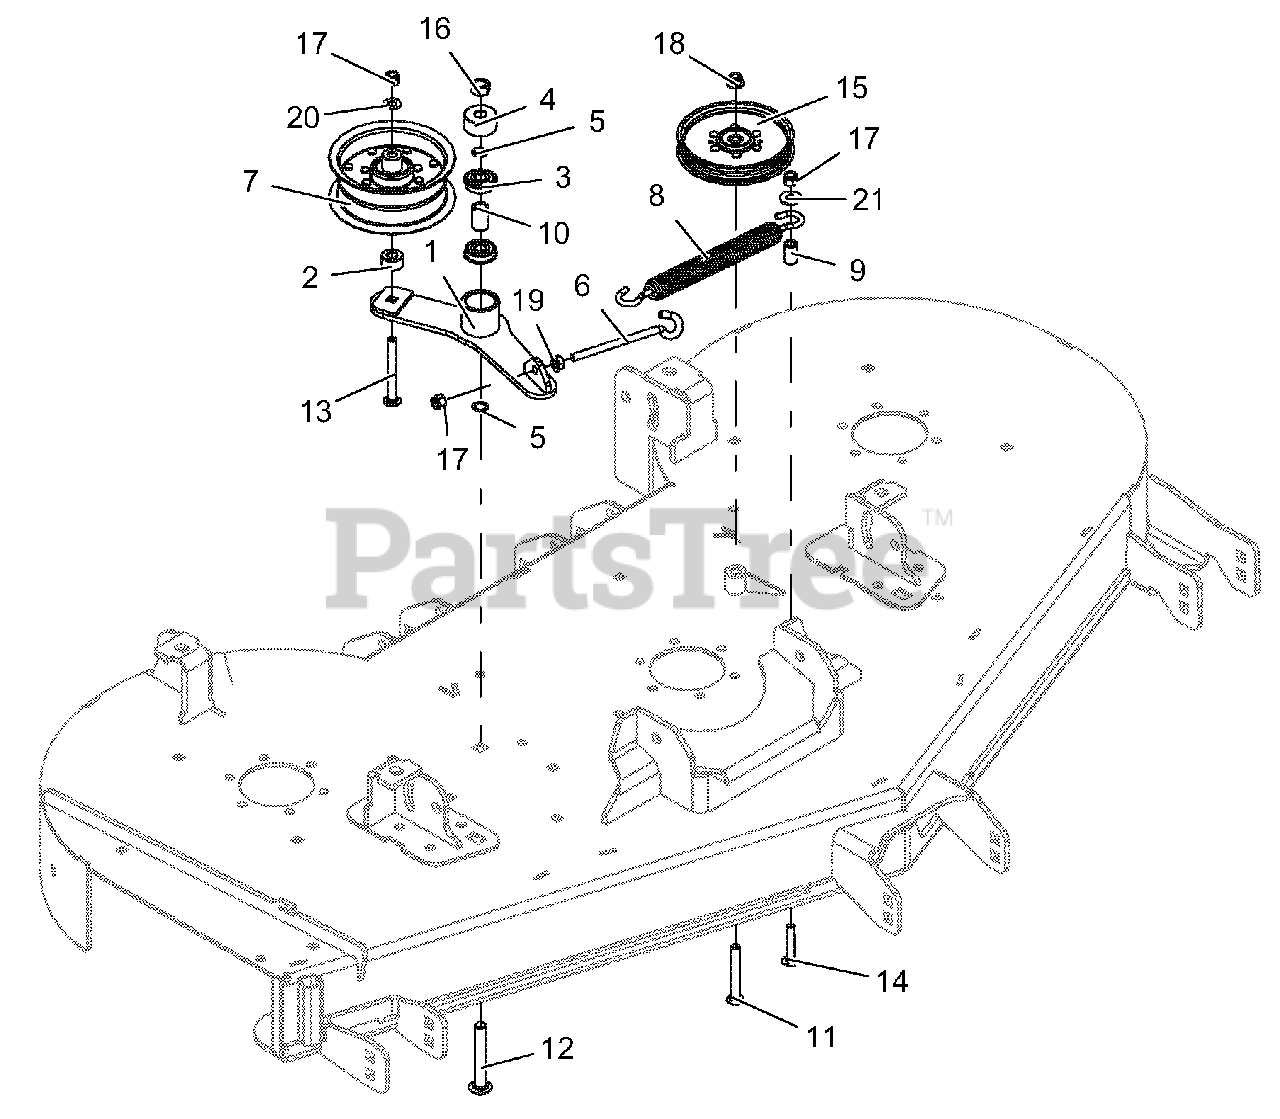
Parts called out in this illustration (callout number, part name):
1	WLDMT, IDLER ARM 61
2	SPACER, .437 x 1.00 x .58 SMLS
3	BRG, BALL .501 x 1.38 x .438 SEALED
4	SPCR, IDLER ARM
5	WASHER-FLAT-STL, .500 x .750 x .020
6	BOLT, EYE .38-16 x 6.00 .62 DIA
7	PULLEY, FLAT 5.00 x 2.36 x .375
8	SPRG, EXTENSION
9	BUSH., S .391 x .622 x .95 ST REV A
10	SPACER, .510 x .750 x 1.148
11	BLT-RDHDSQNK .38-16 x 3.00 G5 YWZC
12	BLT-RHDSSQNK .50-13 x 3.50 G5YZ
13	BLT-RHDSSQNK .38-16 x 3.50 G5YZ
14	BLT-RHDSSQNK .38-16 x 2.00 G5YZ
15	PULLEY, FLAT IDLER .500 x .375 W/BRG
16	NUT-LK-CTR .50-13 YWZC
17	NUT-LK-NYL .38-16 YWZC
18	NUT-LK-NYL-FLG .38-16 YWZC
19	@NUT-SPNLK-FLG .375-16 YWZC
20	WSHR-FL-STL .406 x .812 x .065 YWZ
21	WSHR-FL-STL .438 x 1.00 x .083 YWZC
